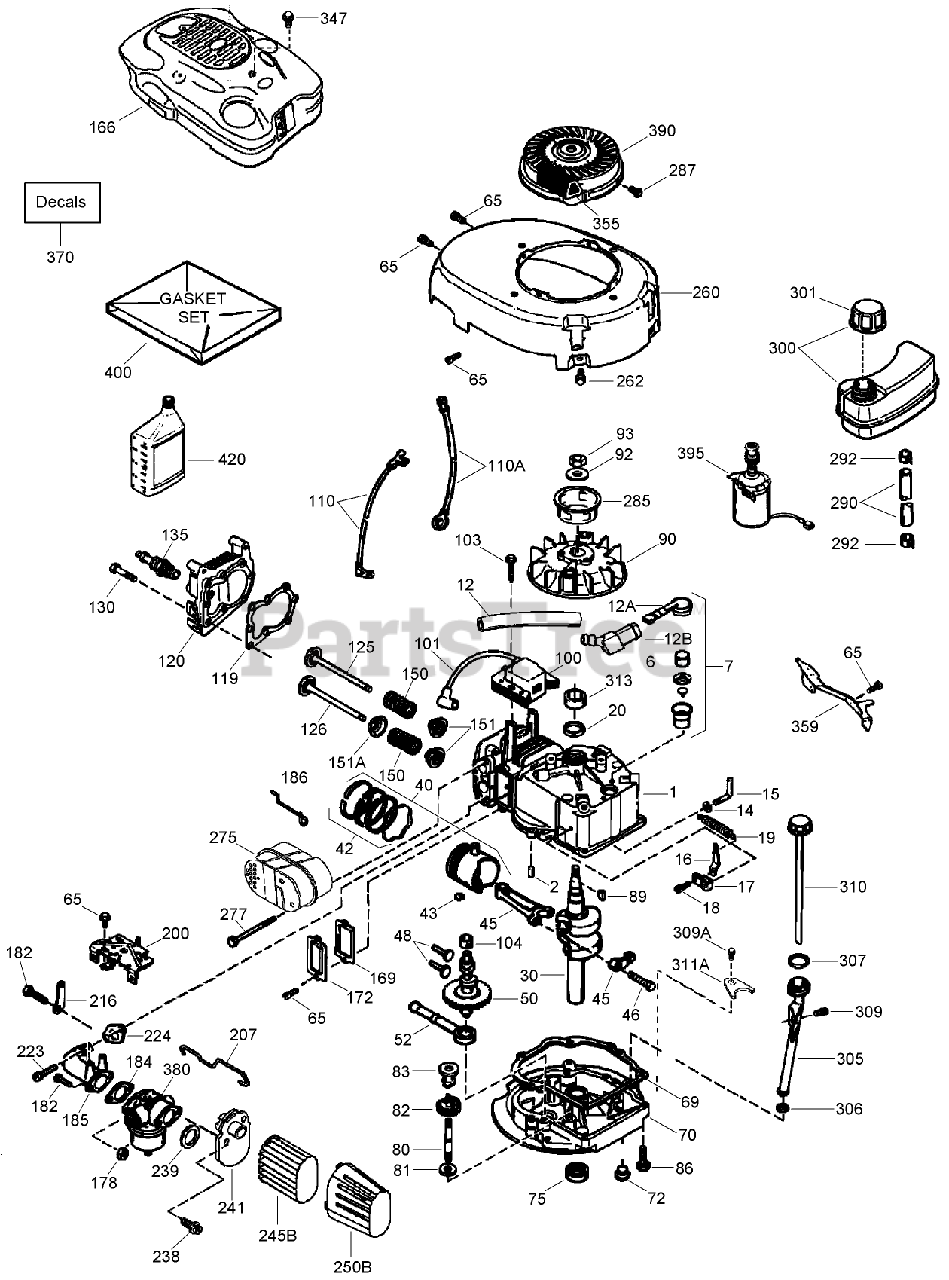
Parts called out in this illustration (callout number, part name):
166	Shroud-Engine
169	Gasket-Cover, Valve
172	Cover-Valve
178	Nut and Lock Washer (1/4-28)
184	Gasket
185	Pipe-Intake
186	Link-Governor
200	Bracket-Control
207	Link-Throttle
216	Lever-Adjusting, R P M
223	Screw (1/4-20 x 1)
224	Gasket-Pipe, Intake
238	Screw (10-32 x 49/64)
239	Gasket-Cleaner, Air
241	Collar-Cleaner, Air
245B	Filter-Cleaner, Air (Paper)
250B	Cover-Cleaner, Air
260	Housing-Blower
262	Screw (1/4-20 x 1/2)
275	Muffler
277	Screw (1/4-20 x 2-9/32)
285	Cup-Starter
287	Screw (8-32 x 21/64)
290	Line-Fuel, Low Permeation (8.62)
292	Clamp-Line, Fuel
300	Fuel Tank ASM
301	Cap-Fuel (Black) (1-1/2 I D)
305	Oil Fill Tube (Incl. 306)
306	O-Ring
307	O-Ring
309	Screw (10-32 x 1/2)
309A	Screw (10-24 x 3/4)
310	Dipstick
311A	Bracket-Holddown
313	Spacer
347	Screw (10-32 x 27/32)
355	Handle-Starter (STD)
359	Flywheel Guard
370	Decal-Warning
370	Decal-Primer
380	Carburetor ASM
390	Rewind Starter ASM
395	Motor-Starter, Electric (12 Volt)
400	Gasket Set
420	Oil-Engine (4-Cycle SAE 30)
